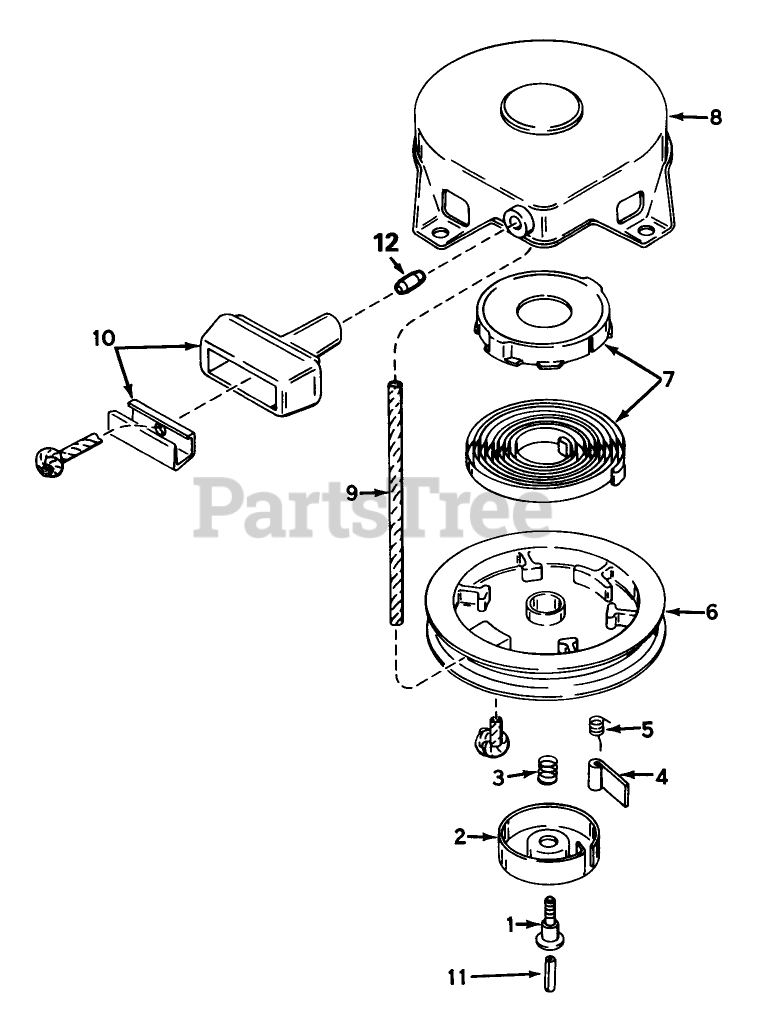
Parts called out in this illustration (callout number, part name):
1	Screw
2	Retainer
3	Spring-Brake
4	Dog-Starter
5	Spring-Dog
6	Pulley
7	Spring Keeper Assy
8	Housing Assy., Starter (Incl. Ref. #1)
9	Rope-Starter (98 cut to length)
10	Assy., Starter
11	Centering
12	Retainer-Starter Rope
